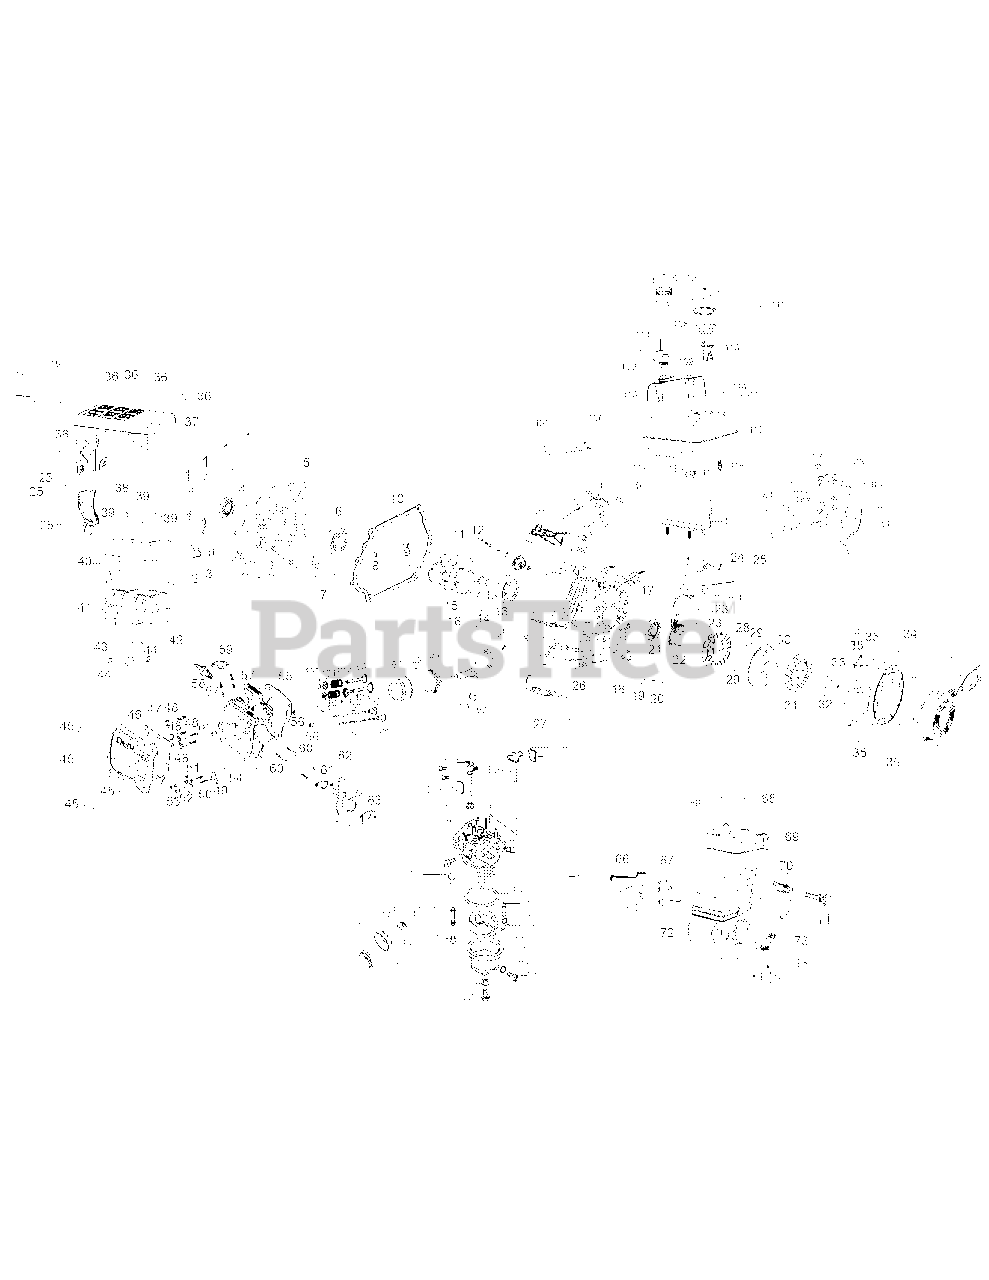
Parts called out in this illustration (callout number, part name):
1	Bolt
2	Oil Filler Plug
3	O-ring
5	Crankcase cover
6	Radial Ball Bearing
7	Camshaft Assembly
10	Crankcase Cover Gasket
11	Crankshaft Complete
12	Governor Kit
13	Radial Ball Bearing
14	Pin Lock
16	Governor Arm
17	Crankcase
18	Oil-Draining Pipe
18	Oil Drain Assembly
22	Ignition Module
28	Stator
30	Flywheel
31	Cooling Fan
32	Starter Cup
37	Muffler Shroud
40	Muffler Shield
41	Muffler Complete
42	Gasket
47	Valve Cover Gasket
49	Plate Push Rod Guide
50	Pivot Bolt
51	Rocker Arm
52	Valve Adjusting Nut
53	Pivot Locking Nut
54	Cylinder Head Complete
55	Cylinder Head Gasket
57	Muffler Stud Assembly, 8 × 34
58	Spark Plug
59	Gasket Muffler
61	Insulator Gasket Carburetor
61	Carburetor Insulator Gasket
62	Insulator Carburetor
62	Carburetor Insulator
63	Carburetor Gasket
63	Gasket Carburetor
65	Carburetor Assembly
66	Choke Push Rod
69	Air Filter Heating Pipe Cover
70	Key Switch
71	Key
72	Shroud
73	Choke Knob
77	Spring Governor
78	Spring Throttle Return
79	Rod Governor
81	Throttle Control Assembly
82	Throttle Control Knob
84	Electric Starter, 110v
91	Connecting Rod Assembly
92	Piston Pin Clip
93	Piston
94	Pin Piston
97	Push Rod
97	Push Rod Kit
98	Exhaust Valve
98	Valve Kit
99	Valve Seal
100	Spring Valve
101	Exhaust Valve Spring Retainer
102	Exhaust Valve Adjuster
103	Intake Valve
104	Internal Valve Spring Retainer
107	Dipstick
108	Dipstick Base
110	Dipstick Decoration Cover
111	Fuel Tank Cap
112	Blower Housing
113	Fuel Filter
115	Fuel Tank
116	Nipple Fuel Tank
117	Fuel Line Kit
121	Recoil Starter AssemblyStarter HandleStarter Handle
122	Fuel Drain Plug
123	Fuel Cup Fixed Bolt Packing
124	Fuel Drain Plug
125	Fuel Drain Plug Gasket
126	Fuel Cup
127	Float
128	Floating Pin
129	Needle Valve Spring
130	Needle Valve
131	O-ring Packing
132	Main Jet
133	Main Nozzle
134	Idle Jet Assembly
135	Idle Speed Adjusting Screw
136	Carburetor Body
137	Fiber Seal
138	Choke Plate
139	Throttle Shaft
140	Choke Plate
141	Choke Shaft
142	Cross Screw
143	Position Spring
144	Clip
145	Fuel Hose
146	Primer Base
147	Primer Bulb
147	Primer
149	Woodruff Key
